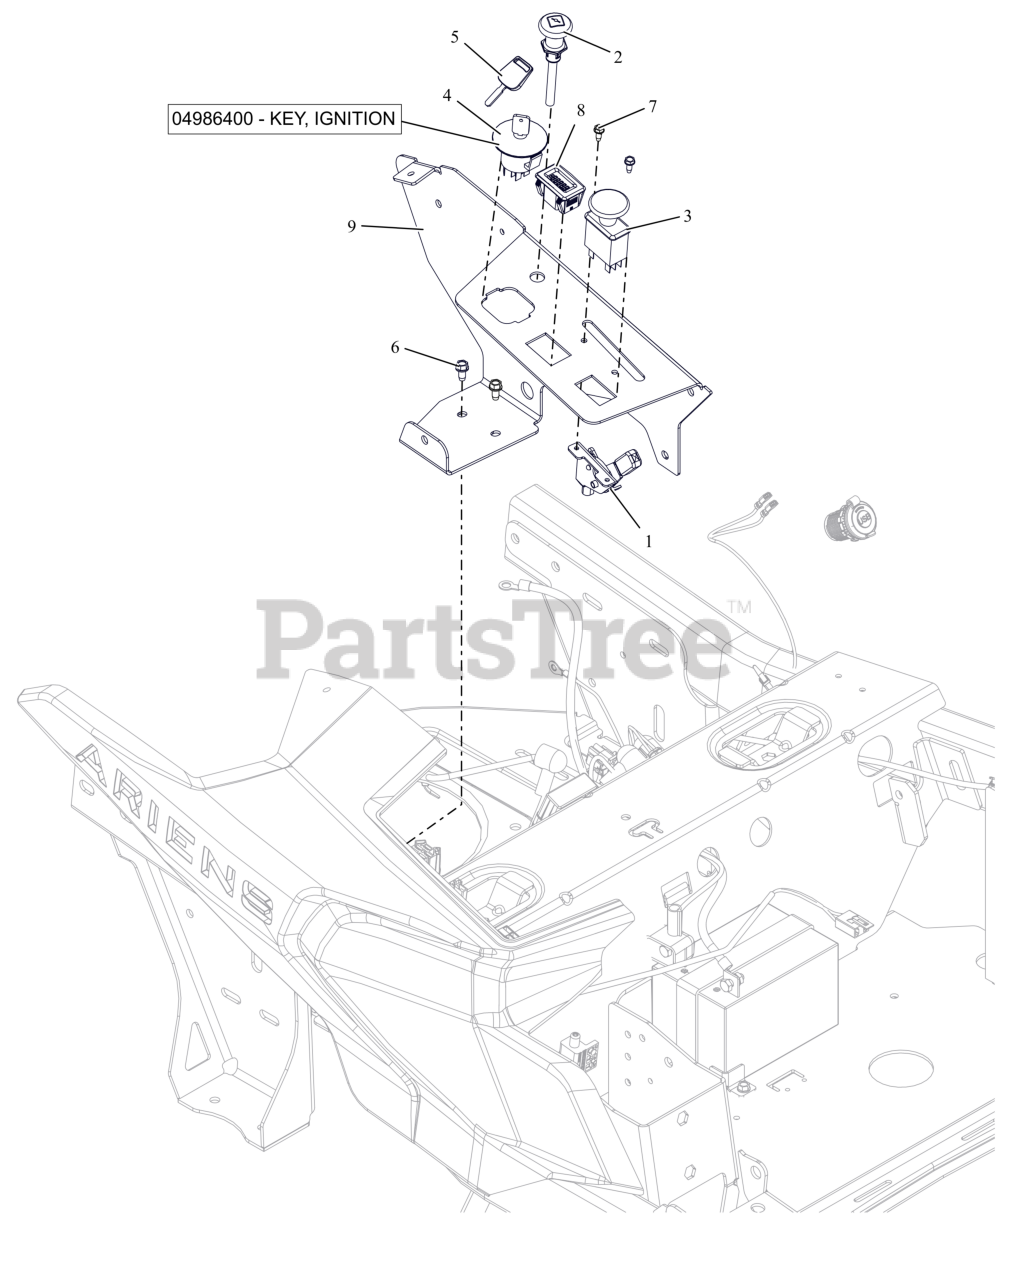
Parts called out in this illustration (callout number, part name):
1	CABLE- THROTTLE LH 90DEG 37"
2	CABLE- CHOKE-SNAP IN 37"
3	SWITCH, CLUTCH
4	KEYSWITCH-IGNITION 4 POS
5	KEY, IGNITION
6	SCR-TAP .25-20X.50 HWH ZCC
7	SCR,TAP #10-24X.50 HWH TR ZCC
8	METER, HOUR - NO PRINT
9	PANEL- CONTROL-RH-ARIENS
